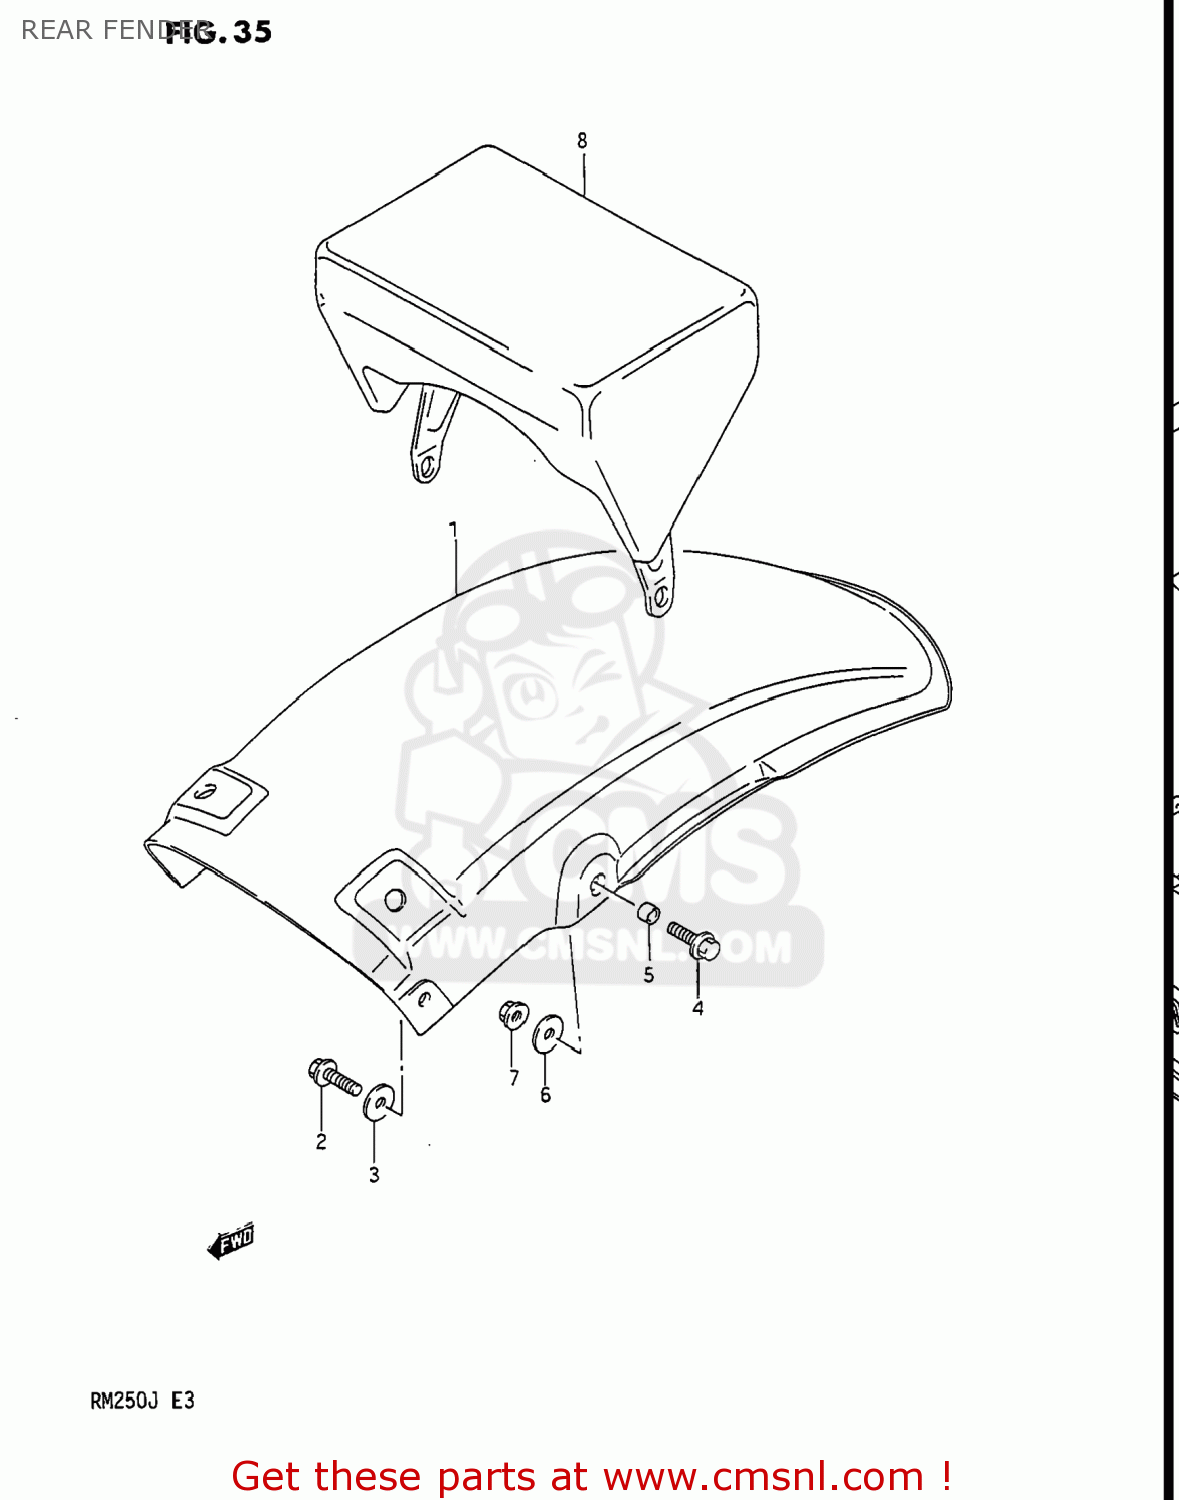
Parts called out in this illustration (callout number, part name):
1	BODY,RR FENDER RR
2	BOLT
3	WASHER (6.5X20X1.2)
4	BOLT
5	SPACER
6	WASHER (6.5X20X1.2)
7	NUT
8	BAG ASSEMBLY,SEAT TAIL
